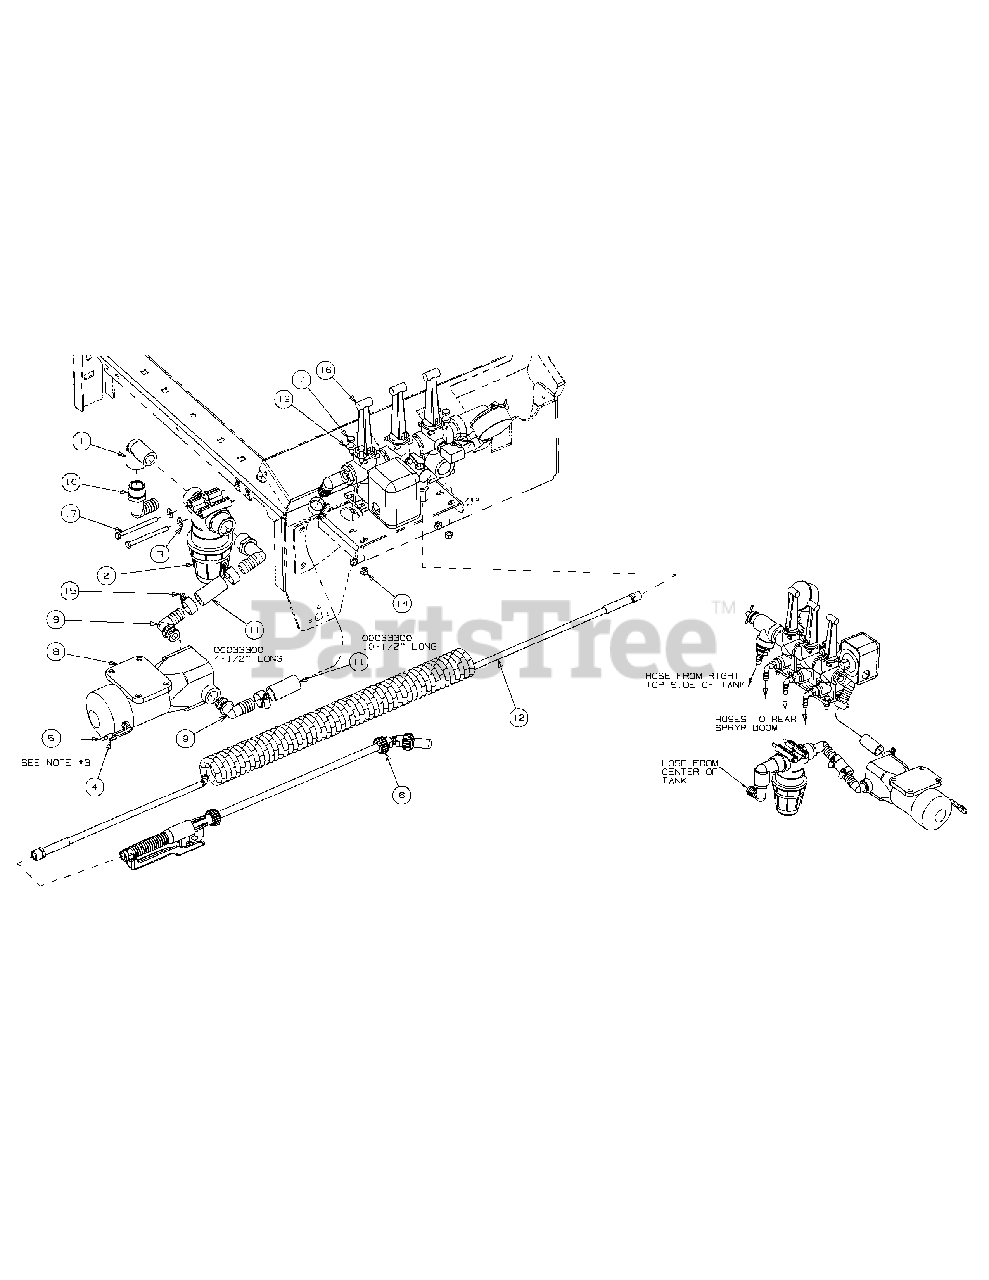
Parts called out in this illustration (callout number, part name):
1	Street Elbow, 3/4 NPT
2	Strainer, 3/4 PVC Line
3	Flat Waser, 1/4 Zinc
4	Connector, Snap Plug, Male
5	Connector, Snap Plug, Female
6	Trigger Jet Spray Gun
7	HHCS, 1/4-20 x 1.00, SS
8	Electric Pump, 4.8GPM 12V
9	Hose Barb, 3/4 90 degree Elbow
10	Elbow, 3/4" x 3/4" MT
11	Hose, 3/4
12	Hose Assembly, 25 ft.
13	Flat Washer, 1/4"
14	Nylock Nut, 1/4-20
15	Hose Clamp, 1/2, 7/8
16	Control Valve Manifold Assembly
17	HHCS, 1/4-20 x 3.00
